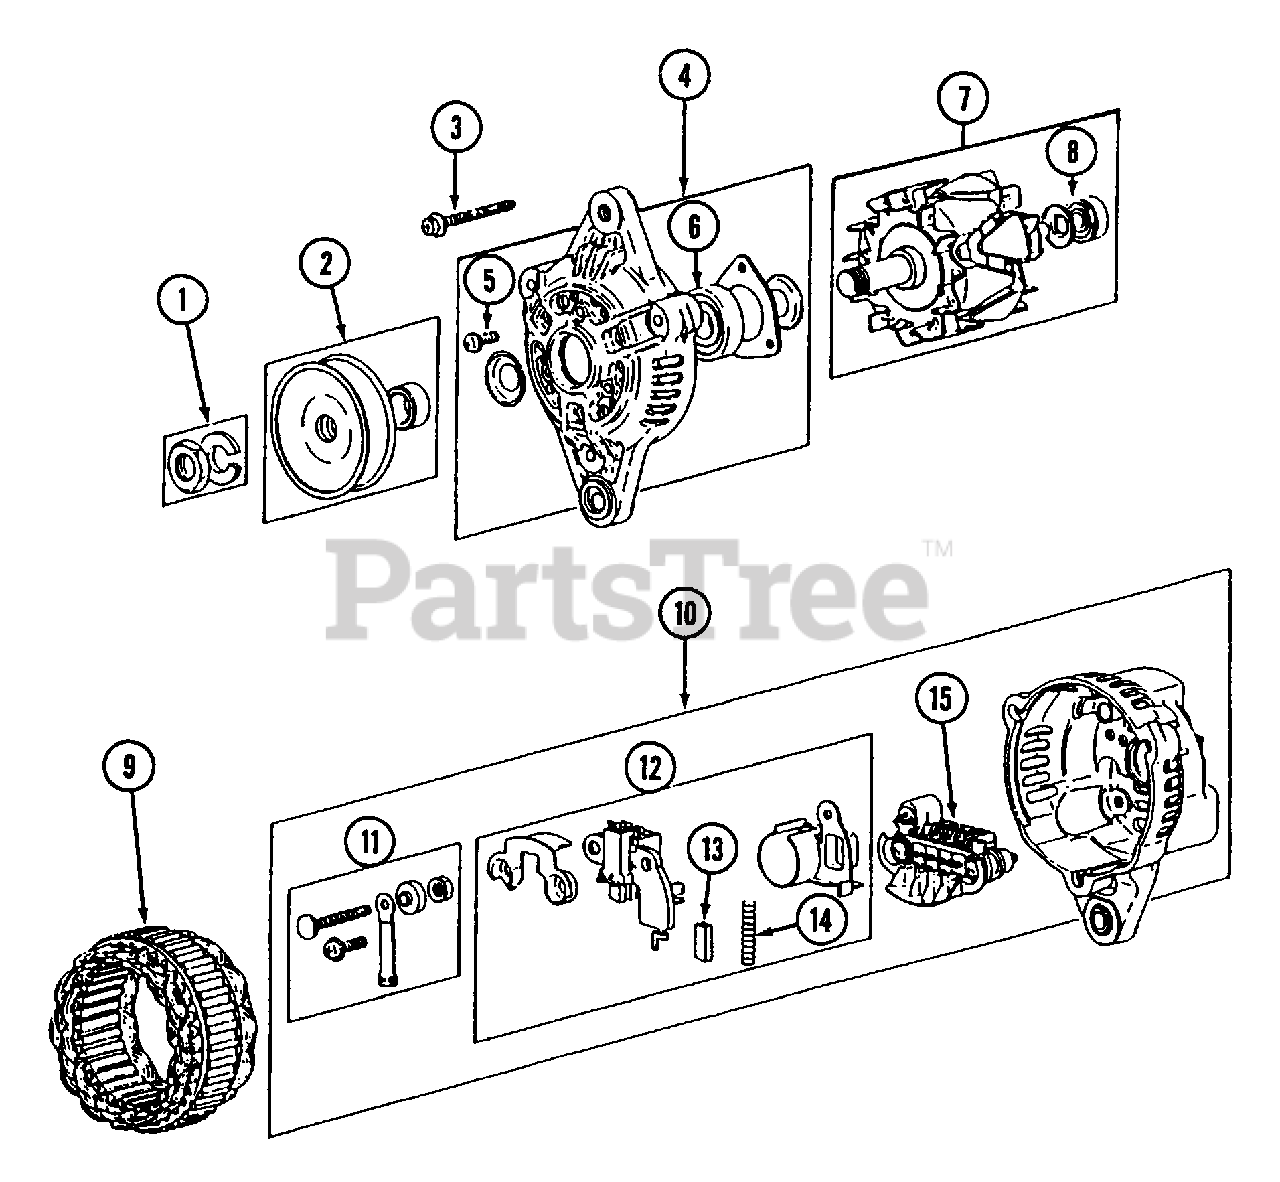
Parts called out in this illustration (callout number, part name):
4	Bracket Ass'y., Front
6	Bearing, Front
7	Rotor Ass'y.
8	Bearing, Rear
9	Starter Ass'y.
10	Bracket Ass'y., Rear
11	Terminal Set
12	IC Regulator Set
14	Spring, Brush
15	Rectifier Ass'y.
